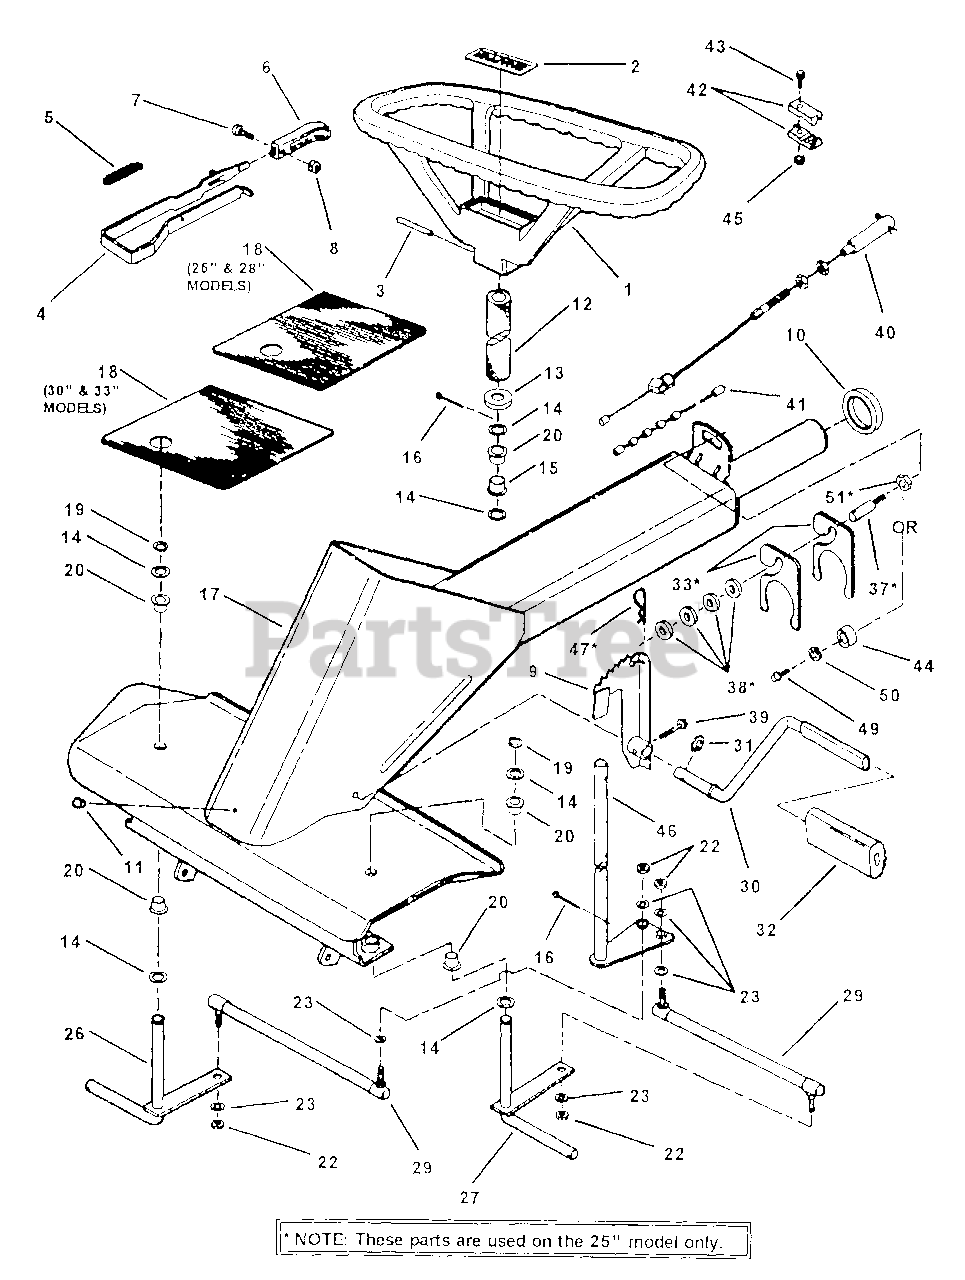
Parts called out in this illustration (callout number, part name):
1	ASSEMBLY, Steering Wheel
2	DECAL, Snapper
3	PIN, 1/4 x 1-1/2" Roll
4	LEVER, Park Brake
5	SPRING
6	KNOB
7	SCREW, #8-32 x 3/8" Cross Recess
8	NUT, #8-32 Hex, Grade 2B
9	ARM, Clutch/Brake (Weldment)
10	SPACER, Main Tube
11	FASTENER/PLUG, Panel
12	COVER, Steering Shaft (Foam)
13	COVER, Steering Shaft
14	WASHER, 3/4" Flat
15	BUSHING, 3/4" Steering Shaft
16	COTTER-PIN, 3/16 x 1-1/2"
17	FRAME, Front (Narrow, 16" @ King Pin Holes)
17	FRAME, Front (Wide, 19" @ King Pin Holes)
18	PAD, Foot (Right Side)
19	RING, 3/4" Retaining
20	BEARING, Nylon
22	NUT, 5/16-24 Hex, Gr. 5
23	WASHER, 5/16" Split Lock
26	PIN, Wide King (Right Side), 11.0" Tires
27	PIN, Wide King (Left Side), 11.0" Tires
29	TIE-ROD 9.13"
30	PEDAL, Clutch/Brake
31	RING, 5/8" External Retaining
32	PAD, Clutch/Brake Pedal
33	SPACER, Pivot
37	STUD, 3/8-24 x 5/8"
38	SPACER (2)
39	SCREW, 5/16-18 x 1-1/4" Hex Washer Self-Tapping
40	CABLE, Brake (Snap-in)
41	CABLE, Clutch 48.71" Long
42	CONNECTOR, Cable
43	SCREW, 1/4-20 x 3/4" Hex Head Cap, Grade 5
44	SPACER, .39 x .625 x .19" Sintered Iron
45	NUT, 1/4-20 Hex Center Lock
46	SHAFT, Steering (Wide Front End)
47	HAIRPIN, 1/8 x 2-9/16"
49	SCREW, 3/8-16 x 5/8" Hex Washer Self-Tap
50	WASHER, 3/8" Flat
51	NUT, 3/8-24 Hex Nyloc
